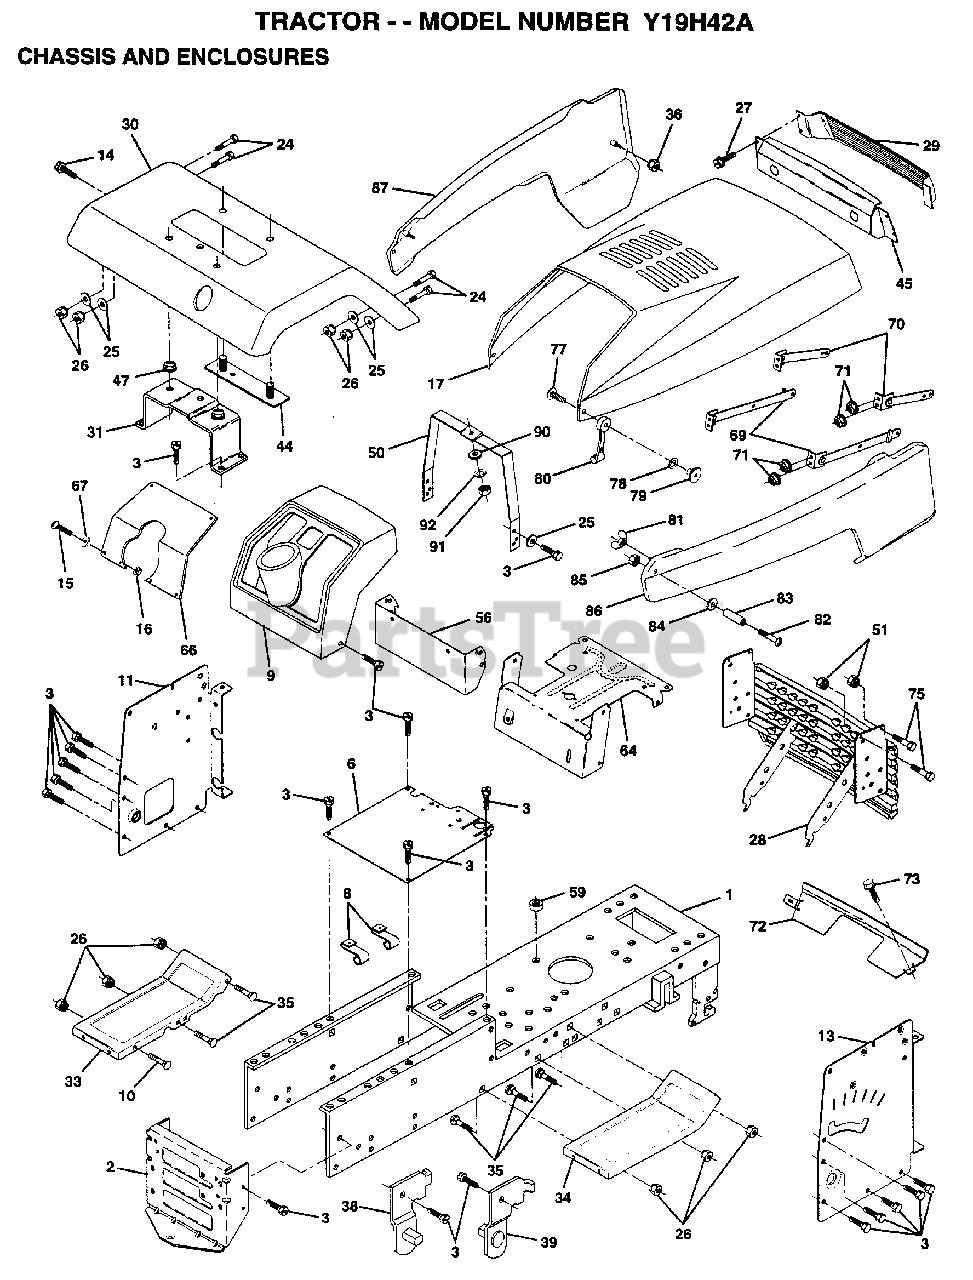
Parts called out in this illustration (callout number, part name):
1	HOUSING.L.50074RM
2	HOUSING.UP.70125
3	SEAL.9008000-0128
4	RING.RET.2003016.
5	RING.RET.2003052.
6	BEARING.(50552)42X68X16
7	CRADLE- 2003023.
8	BEARING.2003044.
9	SWASHPLT.2003087.
13	BLOCK.CLYN.70079.
14	ARM.TRUN.2003005.
15	SEAL.9008000-0126
17	GUIDE.2000015.
18	SHAFT.MOTOR.50115
19	BEARING.THS.50019
23	BLOCK.CYLIN.70082
24	SEAL.LIP.45074
25	ACTUATOR.2003555
26	KIT.CENTER.70133
27	SEAL.LIP.45075
28	RING RETAIN 50007
29	WASHER.44872
34	ELEMENT.OIL.44964
35	ARM.BYPASS.50270
36	RING.RETAIN.44870
37	ARM.ACTUAT.23710
38	PIN.ACTUAT.44891
40	NUT.LOCK.HX.50108
41	KIT.BRAKE.70135
43	WASHER HYD 44130
44	DIFFERENTIA.70130
52	WASHER.HYD.50152
53	SEAL.HYDRO.45076
54	O RING.HYD.45077
56	SHAFT.INPUT.50005
58	BOLT.1/4-20.44876
59	PIN.HYDRO.50002
62	ARM.CONTROL.50254
63	PUCK.DAMPER.50281
64	SCREW.SET.50018.
68	SPRING.HYD.50277
69	STUD.5/16-24.DANA
83	JACKSHAFT/PINION GEAR.70132
85	JACKSHAFT.50086
88	SCREW.CAP.50154.
89	WASHER.HYD.50132
90	BEARING.SLV.50118
91	SEAL.WIPER.50941
92	SPRING.2003014.
93	WASHER.2003017
113	CAP.VENT.70109
114	O-RING.ASM.70110
119	SPACER.HYD.50278
134	NUT.CAS.HYD.44142
135	PIN.COT.HYD.44101
